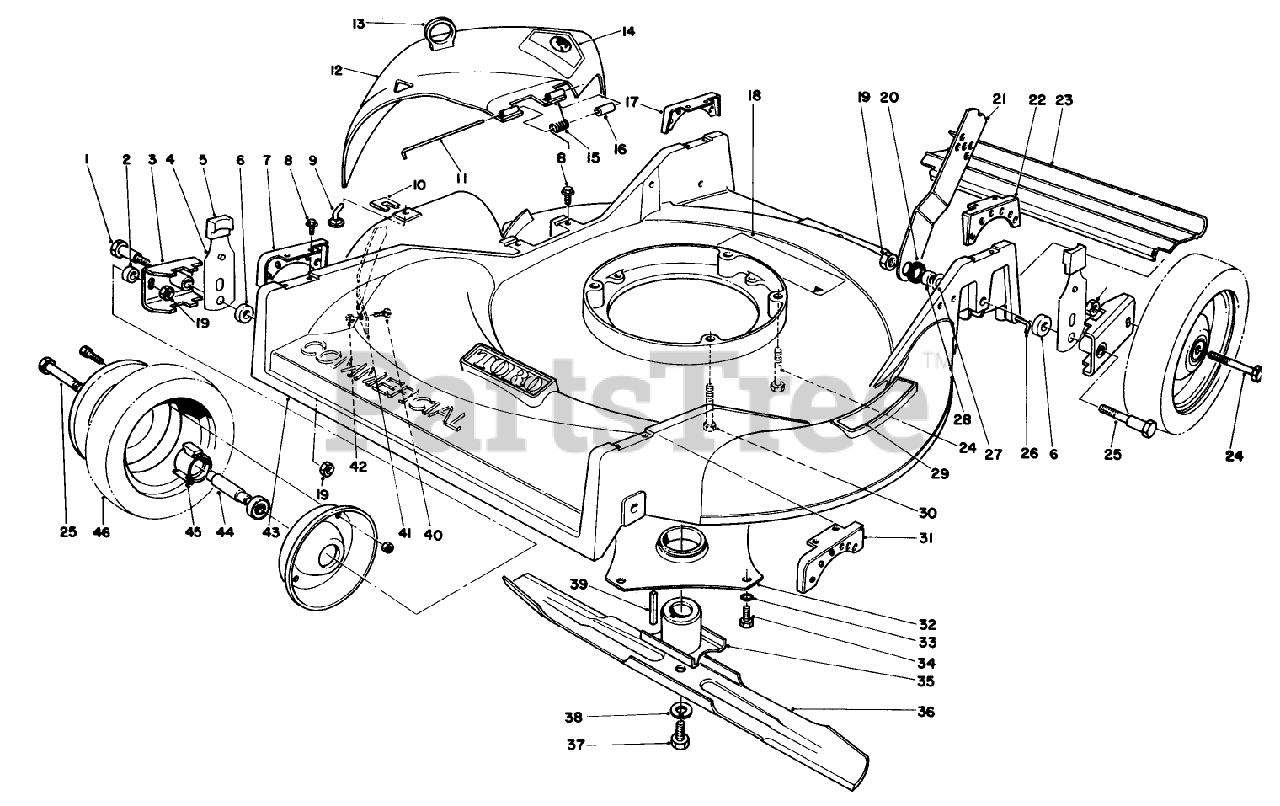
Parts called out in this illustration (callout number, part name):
1	PIVOT SCREW
2	SPACER-WHEEL
3	PIVOT ARM
4	SPRING ARM ASM-FRONT
5	KNOB-ARM
6	SPACER-PIVOT
7	FRT RIGHT QUAD
9	BAG CHUTE PIN
10	BAG CHUTE CLIP PIN
13	LIFT LOOP
14	DECAL-DANGER
15	DEFLECTOR SPRING
19	NUT-LOCK, NI
20	HANDLE LATCH SPACER
24	SCREW-HH
25	REAR PIVOT SCREW
26	SHIELD ROD
27	WASHER-BELLEVILLE
28	HANDLE LATCH SPACER
29	STEP PAD DECAL
30	SCREW-HH
32	CRNKSHFT PROTECT ASM
33	WASHER-LOCK, INTERNAL
34	SCREW-THD ROLL, HWH
37	SCREW-HH
38	WASHER-LOCK
39	KEY-SQUARE
40	SCREW-CARR
42	NUT-LOCK, NI
44	BEARING-WHEEL
45	SPACER-BEARING
